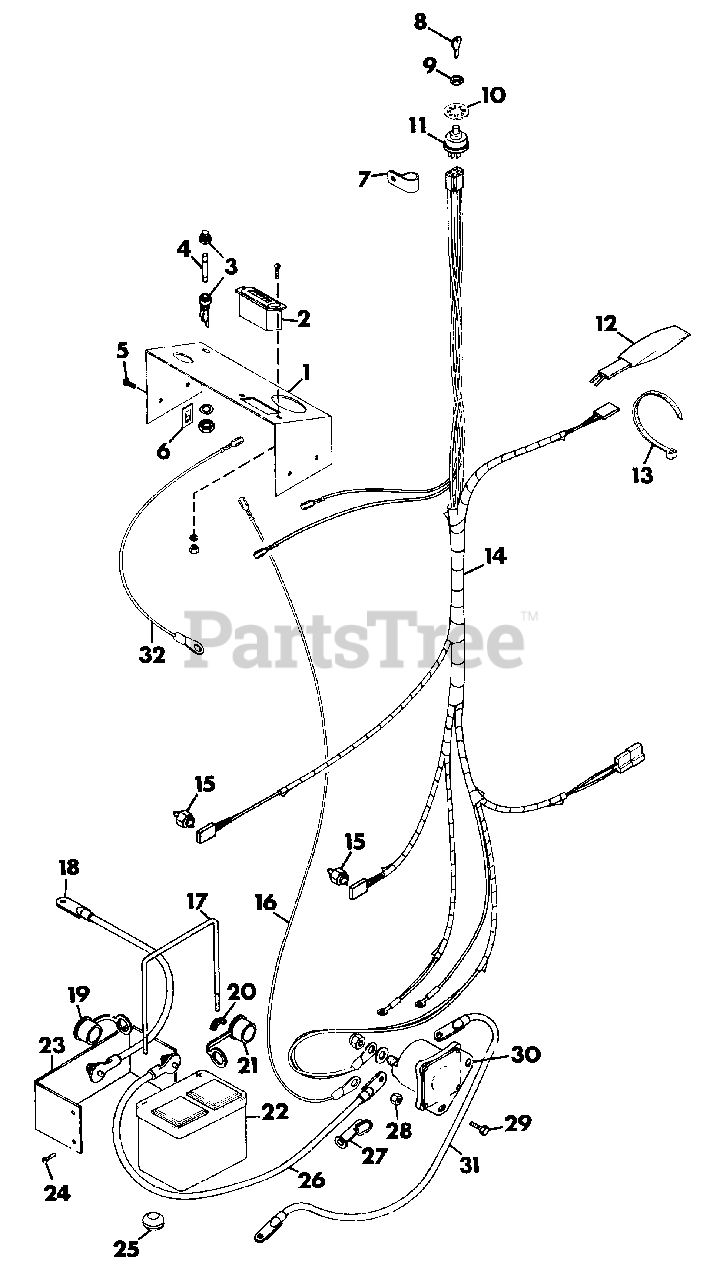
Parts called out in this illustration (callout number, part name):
1	PANEL, INSTRUMENT
2	HOURMETER
3	FUSE, PANEL
4	FUSE, 30 AMP AGC-30
5	SCREW, MACHINE 1/4-20 PAN HD
6	NUT, RETAINER
7	CLAMP, NYLON
8	KEY, IGNITION SWITCH
9	NUT, JAM 9/16-24
10	WASHER, LOCK
11	SWITCH, IGNITION
12	SWITCH, SEAT
13	TIE, CABLE
14	HARNESS, WIRING OFC
15	SWITCH, NEUTRAL START
16	WIRE, FUSE
17	ROD, BATTERY
18	CABLE, ELECTRICAL
19	COVER, BATTERY NEGATIVE TERMINAL
20	NUT, WING 1/4-20
21	COVER, BATTERY POSITIVE TERMINAL
22	BATTERY, 12 VOLT
23	GUARD, BATTERY
24	SCREW, MACHINE 1/4-20X.625
25	GROMMET
26	CABLE, ELECTRICAL
27	BOOT, BATTERY CABLE
28	NUT, LOCK 1/4-20
29	BOLT, HEX 1/4-20X1.00
30	SWITCH, MAGNETIC
31	CABLE, STARTER
32	WIRE, INSTRUMENT PANEL
